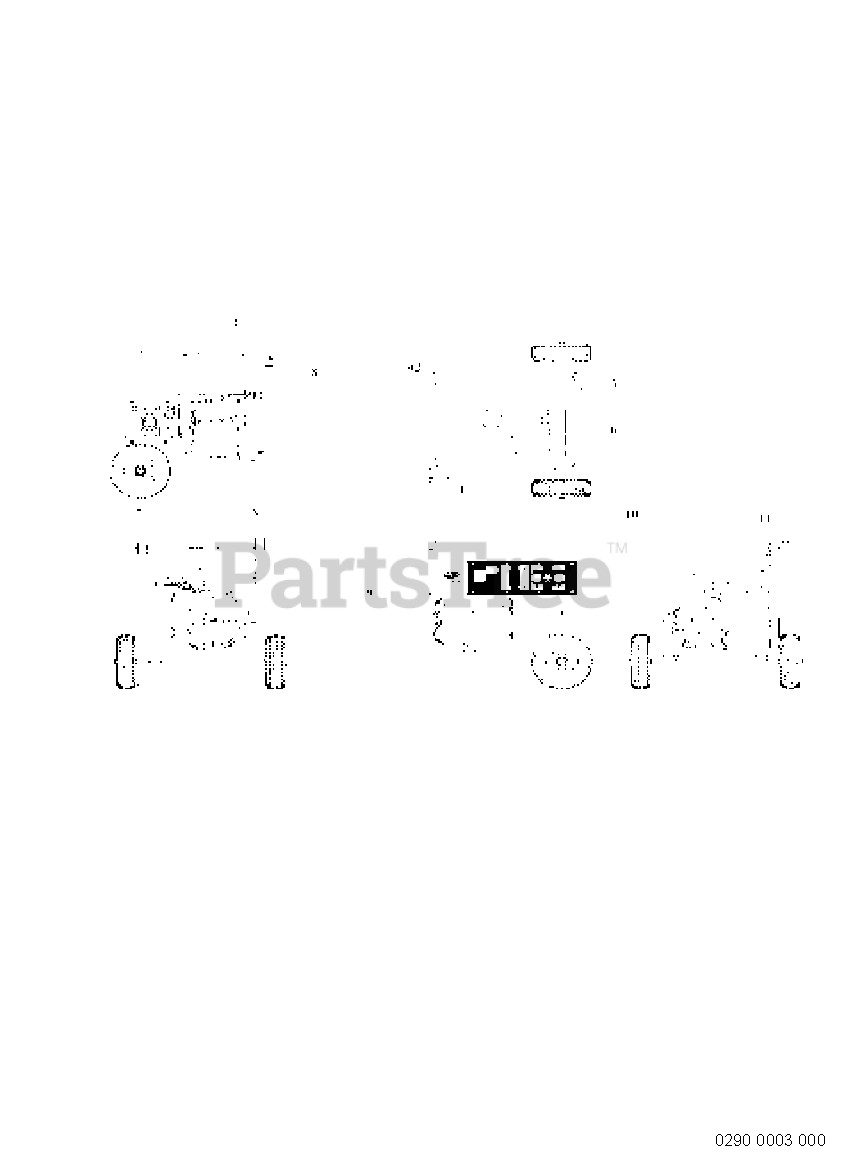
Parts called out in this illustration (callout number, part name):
4	LABEL,OIL LEVEL WARNING
7	LABEL(FUEL COCK)
8	LABEL,TRADE MARK
9	LABEL,TRADE MARK
